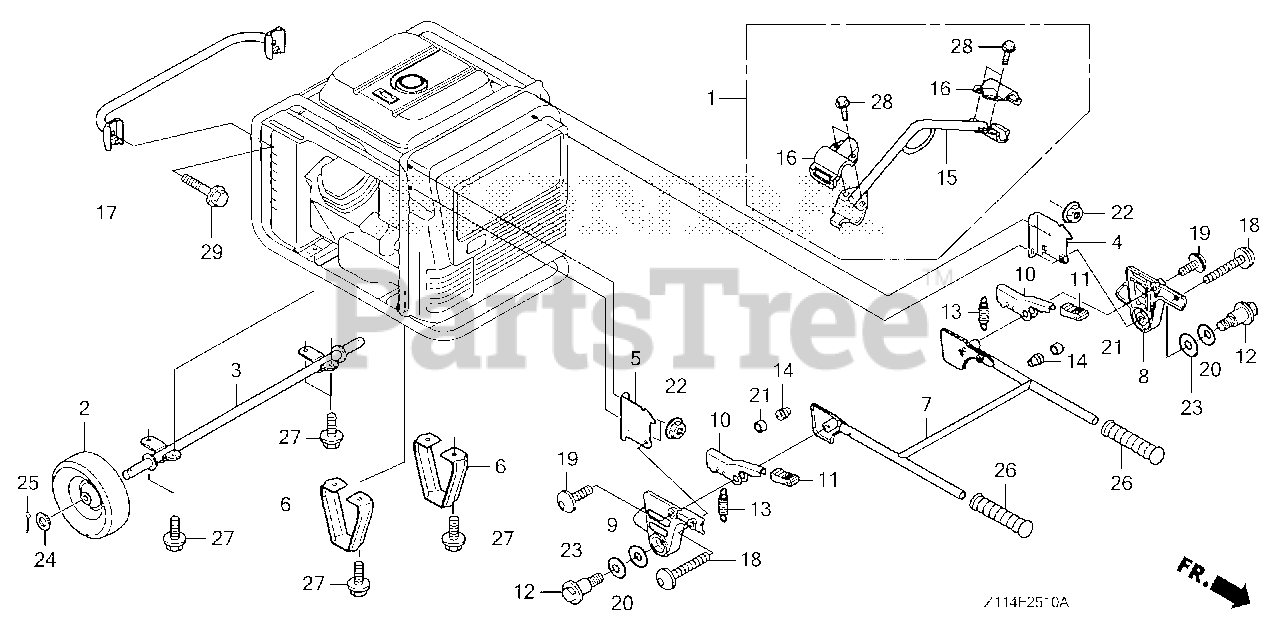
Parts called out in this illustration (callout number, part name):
2	WHEEL (GLEASON 10"X2.75"=254X70)
3	SHAFT, WHEEL
4	BRACKET, R. HANDLE
5	BRACKET, L. HANDLE
6	STAND *NH105* (MAT BLACK)
7	PIPE, HANDLE *NH105*
8	HOLDER, R. HANDLE
9	HOLDER, L. HANDLE
10	LEVER, HANDLE
11	RUBBER, GRIP
12	BOLT, HANDLE HOLDER
13	SPRING, HANDLE LEVER
14	RUBBER, STOPPER
15	HANGER *NH105* (MAT BLACK)
16	BRACKET, HANGER (UPPER)
17	PIPE, RR. *NH105* (MAT BLACK)
18	BOLT, SOCKET (8X45)
19	BOLT, SOCKET (8X22)
20	WASHER, SPRING
21	COLLAR, HANDLE
22	NUT, FLANGE (8MM)
23	WASHER, PLAIN (12MM)
24	WASHER, PLAIN (20MM)
25	PIN, SPLIT (4.0X28)
25	PIN, COTTER (4.0X30)
26	GRIP D, R. HANDLE (BOTH SIDES)
27	BOLT, FLANGE (8X16) Use from Engine SN 1000016.
28	BOLT, FLANGE (8X16)
29	BOLT, FLANGE (8X45)
29	BOLT, FLANGE (8X50)
